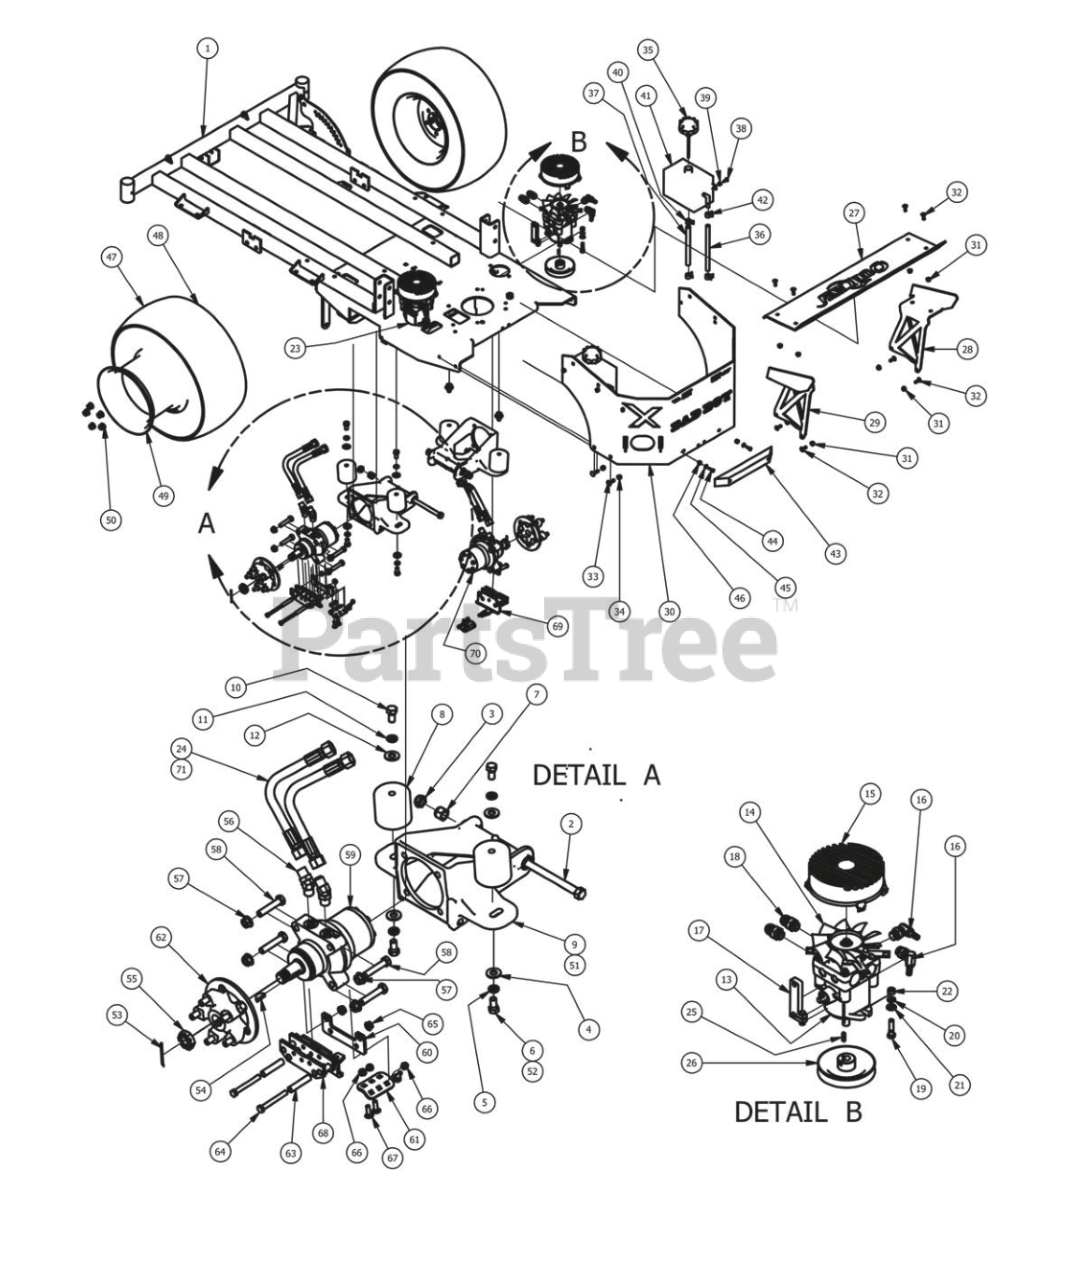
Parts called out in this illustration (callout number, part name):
1	2012 Suspension Outlaw
2	5/8"x10" Hex Bolt (Grade8)
3	5/8" Nylock (1/2 Jam)
4	1/2" Washer (Grade 8)
5	1/2" Lock Washer
6	1/2" x 1" Hex Bolt
7	5/8 Std NC Nylock Nut
8	Vibration Mount-Green Dot
9	60" Suspension Kit Wheel Motor
10	1/2" x 1" Hex Bolt
11	1/2" Lock Washer
12	1/2" Washer (Grade 8)
13	Left Pump 12cc
14	Hydraulic Fan
15	Fan Guard for 10A
16	3/8" X 9/16-18 ORB Male Fitting (S,A-2 P-4)
18	Hydraulic Pump Fitting 6400-10
19	3/8" x 1 1/2" Hex Bolt
20	3/8" Lock Washer
21	3/8" Flat Washer
22	3/8" Hex Nut
23	Right Pump 12cc
24	18" hose Assembly W/forged 45 Degrees
25	5MM X 1 Square Key Stock
26	5" Pump Pulley
27	Outlaw Spoiler Plate
28	Outlaw Susp Spoiler Bracket (Right)
29	Outlaw Susp Spoiler Bracket (Left)
30	Outlaw Rear Cover Plate Susp Frame
31	5/16 Flange Nut Zinc W/Serrations
32	5/16" x 1" Carriage Bolt
33	3/8" x 1 1/4" Carriage Bolt
34	3/8 Nylock Nut
35	Hydraulic Tank Cap W/Dipstick
36	3/8 clear hose price per foot
37	1/2 Clear Braded Hose Priced/Foot
38	1/4" x 3/4" Carriage Bolt
39	1/4-20 Nylon Insert flange Nut
40	1/2 Hose Clamp
41	Outlaw Hydraulic Tank
42	3/8 hose clamp
43	14" Rubber Bumper
44	1/4-20 x 1-1/4 GR 5 Hex Bolt.
45	1/4 Flat Washer
46	1/4-20 Nylon Insert flange Nut
47	24 x 12.00-10 Tire and Wheel assembly
48	24 x 12.00-10 outlaw Tire
49	10" Wheel For Outlaw
50	Acorn Lug Nut
51	72" Suspension Kit Wheel Motor
52	1/2-13 x 1/1/4 Hex Bolt Only on 60" Suspension kit wheel Motor
53	1/8x2-1/4 cotter pin Zinc
54	Woodruff Key
55	1" Castle Nut for Wheel Motor
56	45 Degree Fitting 31704-10-10
57	1/2" Flange Nut
58	1/2" x 2 1/2" Hex Bolt
59	15cc Parker Wheel Motor- Left
60	Ausco Caliper Mounting Bracket
61	Ausco Brake Clable Bracket
62	Drum Brake Hub & Rotor Assembly
63	Ausco Brake Spacer
64	3/8-16x3 grade 5 hex bolt
65	3/8" Flange Nut
66	3/8 Std NC Nylock Nut
67	5/16" x 1" Carriage Bolt
68	Left Brake Caliper
69	Right Brake Caliper
70	15cc Parker Wheel Motor- Right
71	18" Hydraulic Hose Only
